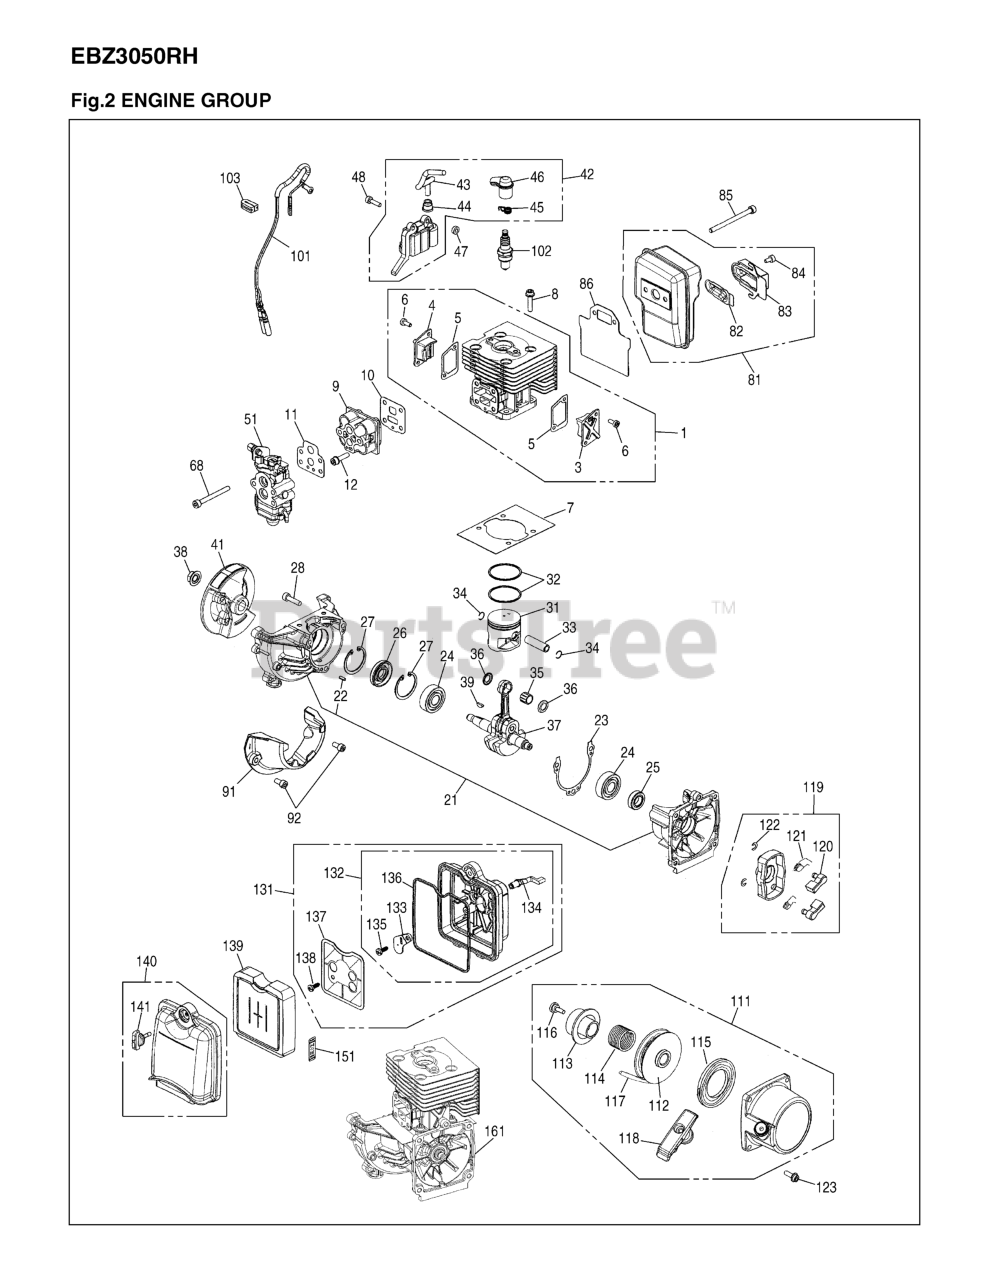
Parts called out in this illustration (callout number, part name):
1	CYLINDER COMP
3	COVER, TR(S)
4	COVER, TR(F)
5	GASKET, TR
6	BOLT
7	GASKET, BASE
8	BOLT
9	INSULATOR
10	GASKET, INSU
11	GASKET
12	BOLT (RPLS 2850-14220)
21	CRANKCASE
22	PIN
23	GASKET, CASE
24	BEARING
25	SEAL
26	SEAL
27	RING, SNAP, M32 x 1.2
28	BOLT (RPLS 2850-14220)
31	PISTON
34	RING, SNAP
35	BEARING
36	WASHER (RPLS 3310-41341)
37	CRANKSHAFT COMP
39	KEY
42	COIL ASSY
47	SPACER (RPLS -71260)
48	BOLT TORX
51	CARBURETOR ASSY
68	BOLT
81	MUFFLER
82	ARRESTER
84	Bolt
85	BOLT
86	GASKET
92	BOLT
101	CORD COMP
102	SPARK PLUG (CMR7H)
103	GROMMET
111	RECOIL ASSY
112	REEL
113	PLATE, CAM
114	SPRING, DAMPER
115	SPRING, SPIRAL
116	SCREW
117	ROPE
118	KNOB (RPLS -75420)
119	PULLEY ASSY
120	RATCHET
121	SPRING
122	E-RING
123	BOLT, TORX
131	BODY & SCREEN
132	BODY ASSY
133	PLATE, CHOKE
134	LEVER
135	SCREW
136	PACKING
137	SCREEN (REPLACES -83K1)
138	SCREW
139	ELEMENT
140	COVER ASSY
141	KNOB (RPLS -82220)
151	LABEL, CHOKE
161	SHORT BLOCK KIT
